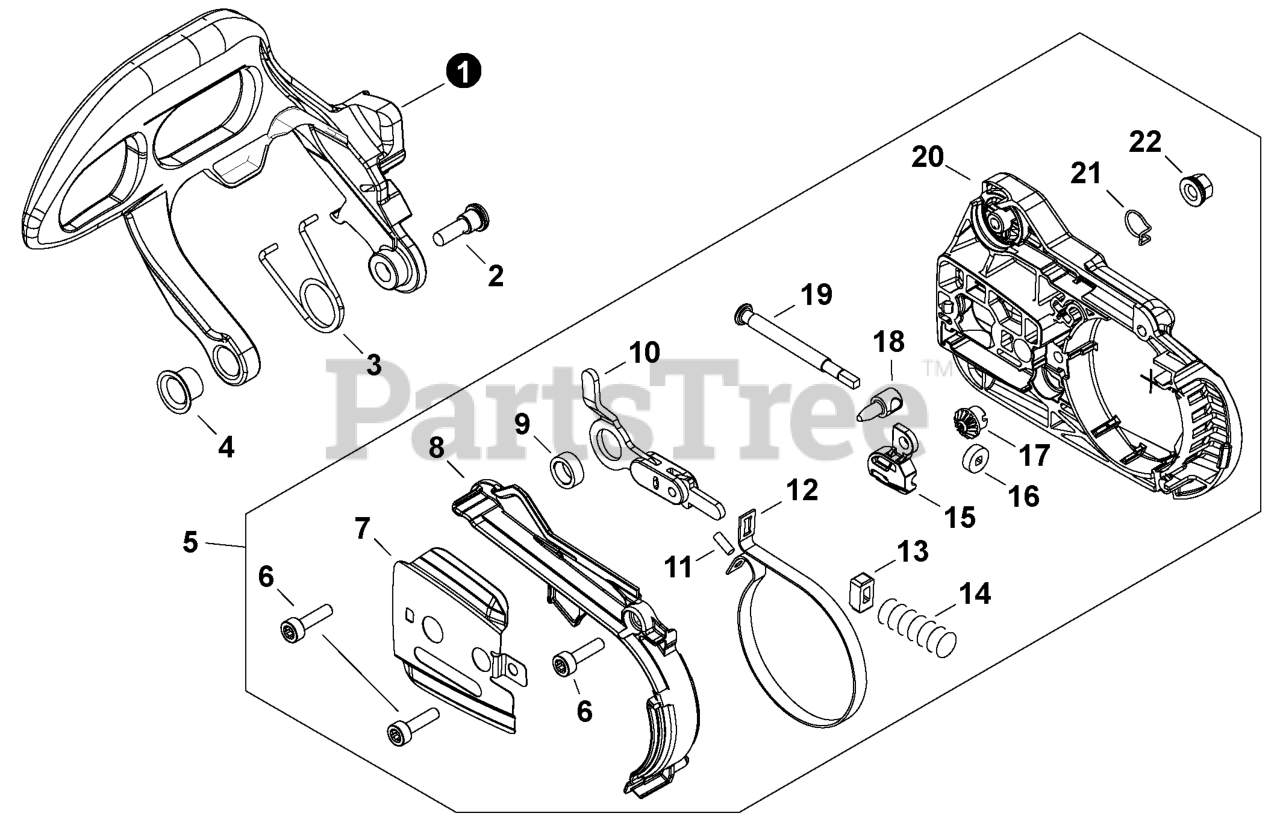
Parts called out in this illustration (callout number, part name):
1	LEVER, BRAKE
2	BOLT 5x13
3	SPRING, TORSION
4	COLLAR 10
5	SPROCKET GUARD ASSY
6	BOLT, TORX 4x12
7	PLATE, GUIDE - OUTER
8	COVER, BRAKE
9	COLLAR 8
10	CONNECTOR, BRAKE
12	BAND, BRAKE
14	SPRING, COMPRESSION
15	COLLAR 8
16	GEAR, BEVEL
17	GEAR, BEVEL
18	TENSIONER, CHAIN
20	GUARD, SPROCKET
